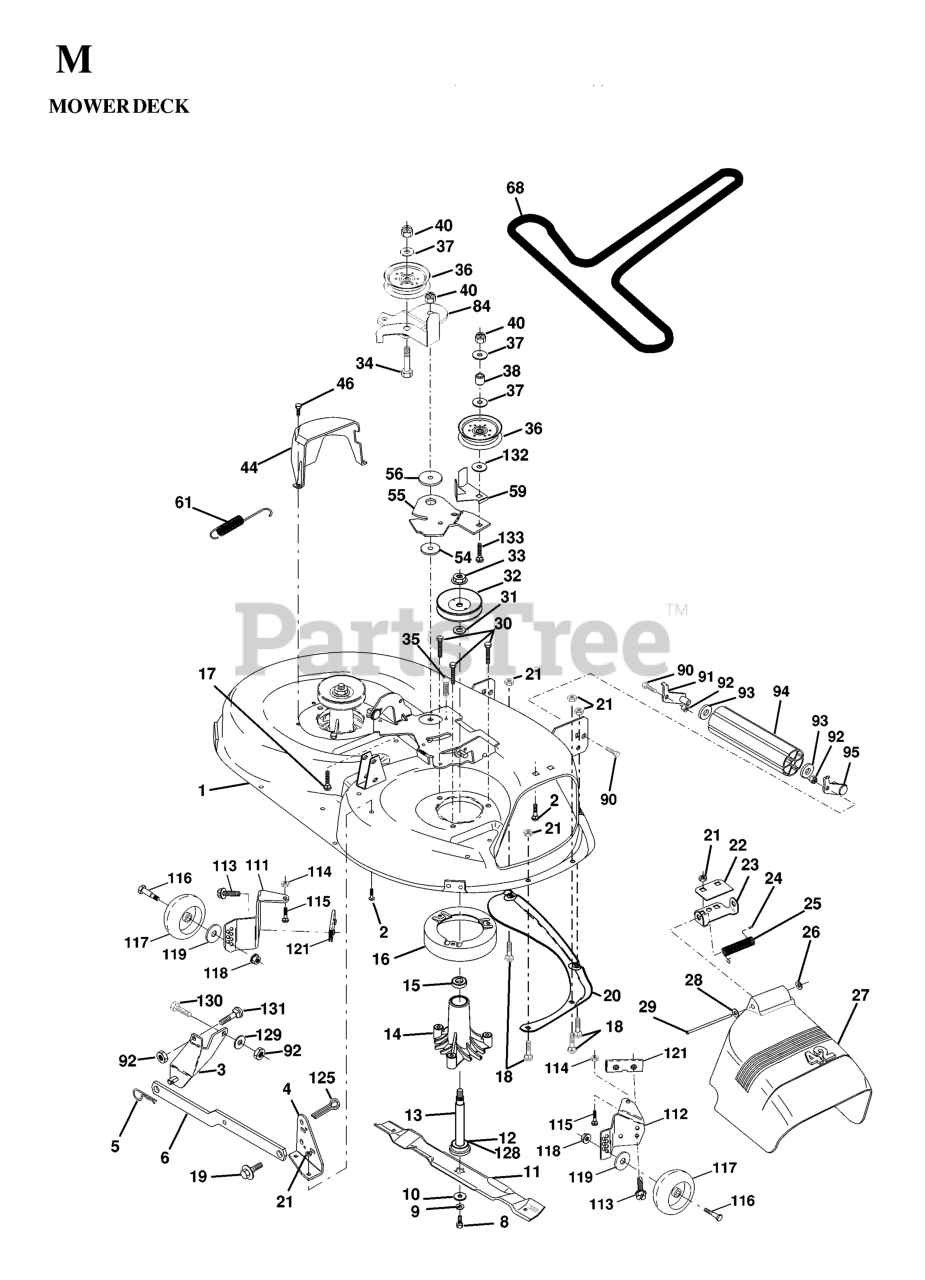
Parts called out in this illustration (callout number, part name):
1	DECK 42"
2	RP BOLT 5/16-18 X3/4 ZN/YEL GR
3	BRKT ASM SWAY BAR
4	BRKT DECK SW BAR
5	RETAINER-SPRNG RB
6	REAR SUSP ARM
8	BLADE BOLT
9	LOCKWASHER
10	WASHER.BLADE
11	BLADE 42", YTH 160
12	BEARING.BALL.#6204.(MANDREL)
13	SHAFT ASM VENT
14	HOUSING.MANDREL.VENTED (MACHD)
16	STRIPPER
17	BOLT CARRIAGE
18	BOLT
19	BOLT SHD 5/16-18
20	BAFFLE
21	LOCKNUT
22	STIFFENER BRACKET
23	DEFLECTOR BRACKET
24	CAP-SLEEVE LT
25	SPRING TORSION
26	NUT PUSH M
27	SHIELD.DEFLECTOR.MOWER.42".BLK
28	Washer 11/32 x 5/8 x 16 Ga SD
29	ROD.HINGE
30	SCREW
31	WASHER
32	PULLEY/MANDREL
33	NUT
35	FASTENER.XMAS.TREE
36	FLAT IDLER PULLEY
37	WASHER
38	IDLER SPRING SPACER
44	GUARD MANDREL LH BLACK
46	SCREW.1/4-20X5/8
54	HARDENED WASHER
55	IDLER ARM
56	SPACER RETAINER
59	GUARD, BELT
61	SPRING EXTENSION
84	KEEPER.BELT.IDLER
85	BOLT
90	BOLT
91	BRACKET LH (A)
92	NUT
93	Washer 1 17/32 X 7/8 X 16 Ga
94	NOSE ROLLER
95	BRACKET RH (B)
111	BRACKET WHEEL GAUGE LH 42" DK
112	BRACKET WHEEL GAUGE RH 42" DK
113	SCREW.THDROL.5/16-18X3/4.TTY
114	NUT
115	BOLT.CARR.5/16-18X1/2
116	BOLT, SHOULDER
117	WHEEL GAGE DONUT
118	LOCKNUT
119	WASHER.5/16.FLAT.STE.STD.
121	BRACKET.EXTRUDED.GAGE.WHEEL
125	Pin Cotter 1/4 x 1 Plated
128	WASHER FELT
129	WASHER
131	BOLT D
132	Washer 13/32 x 1-3/8 x 13 Ga.
